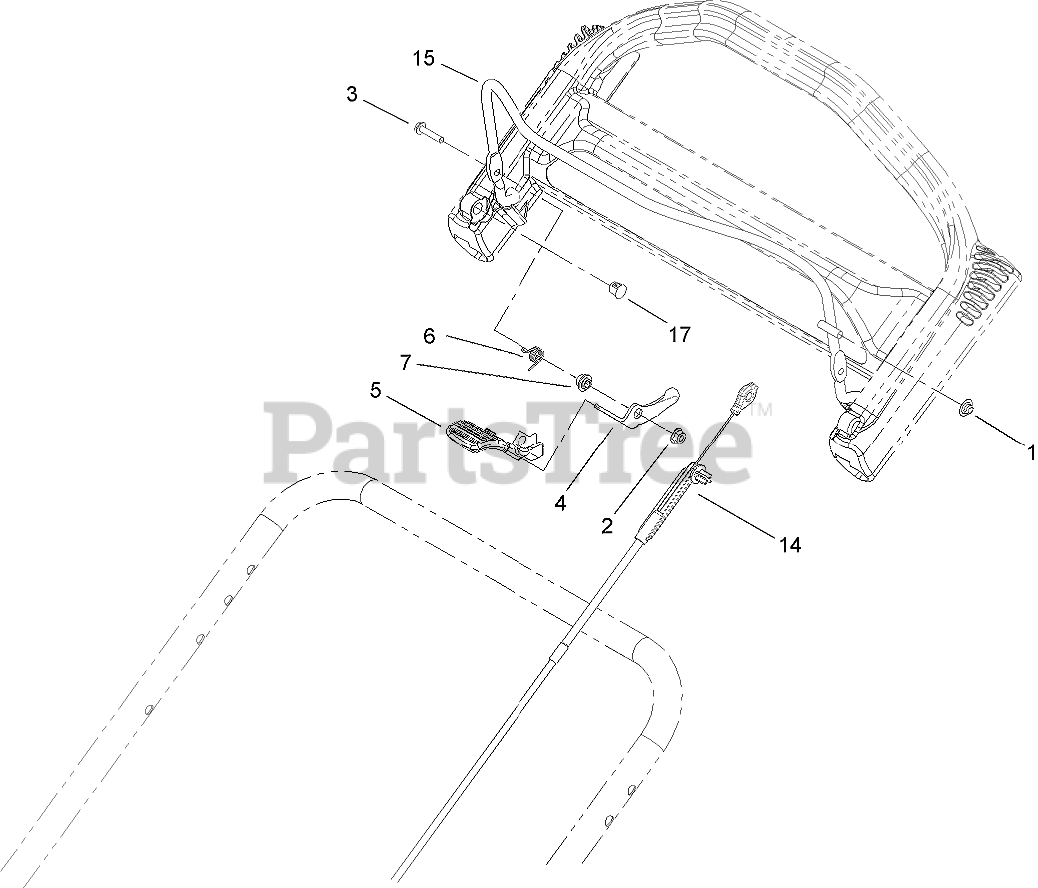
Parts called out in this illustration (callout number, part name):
1	NUT-SPEED
2	NUT-LOCK, FLANGE
3	SCREW-HWH
4	LEVER
6	SPRING-TORSION
7	SPACER
14	CABLE ASM
15	BAIL-BRAKE
17	Plug-Dome
